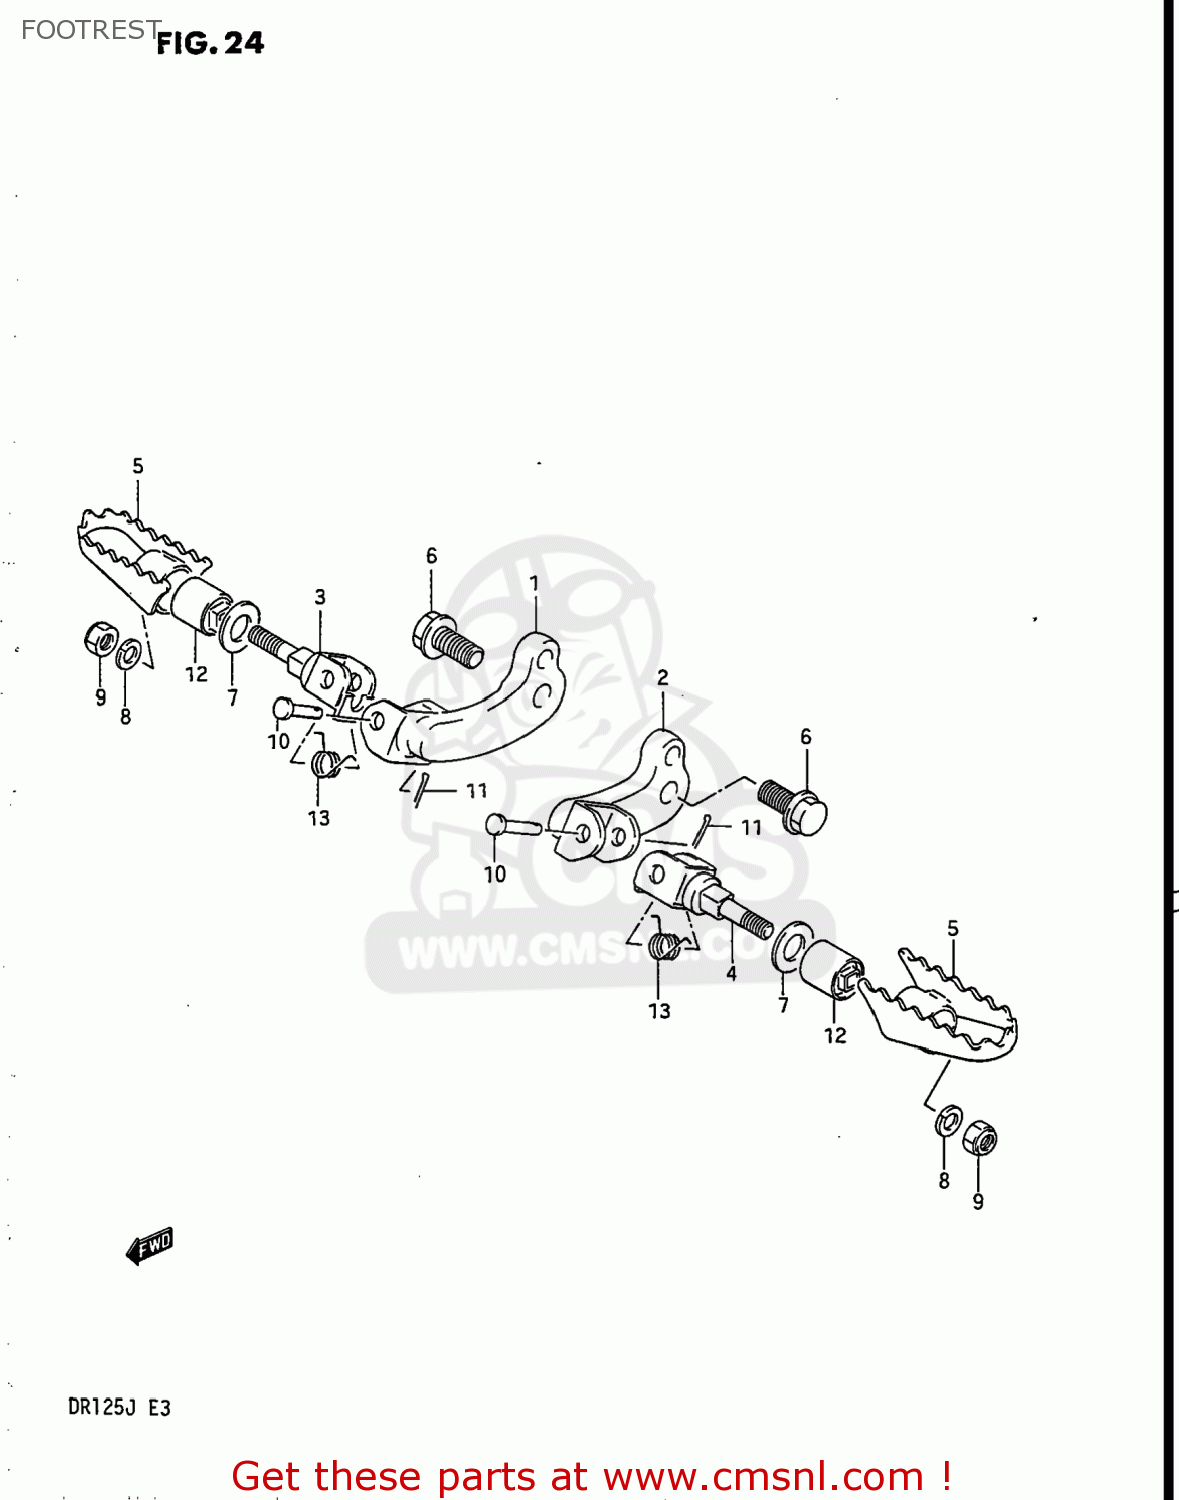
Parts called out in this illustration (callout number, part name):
1	BAR,FRONT FOOTREST
2	BAR,FRONT FOOTREST,LEFT
3	BRACKET,FRONT FOOTREST
4	HOLDER COMP,FRONT FOOT
5	FOOTREST,FRONT
6	BOLT
7	WASHER
8	WASHER,LOCK
9	NUT
10	PIN
11	PIN
12	BUSH
13	SPRING
